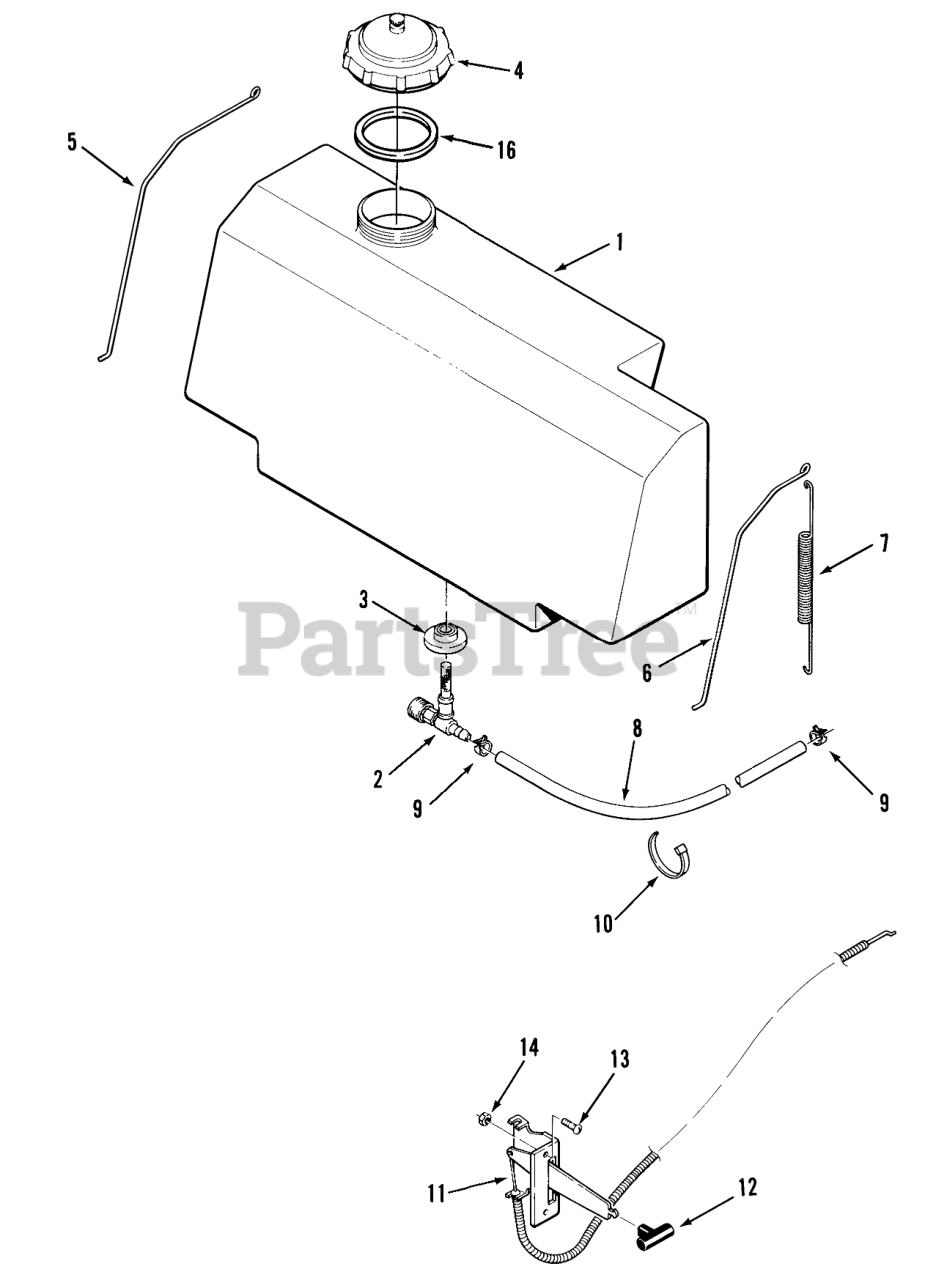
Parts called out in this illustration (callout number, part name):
1	Fuel Tank (includes items 2 & 3)
2	VALVE-FUEL
3	BUSHING
4	ASSY FUEL CAP
5	RETAINER TANK RH
6	RETAINER TANK LH
7	SPRING EXTENSION
8	Hose
9	Clamp
10	PLASTIC TIE
11	CONTROL-THROTTLE
12	KNOB-CONTROL
13	Screw
14	Nut
16	GASKET-GAS CAP
